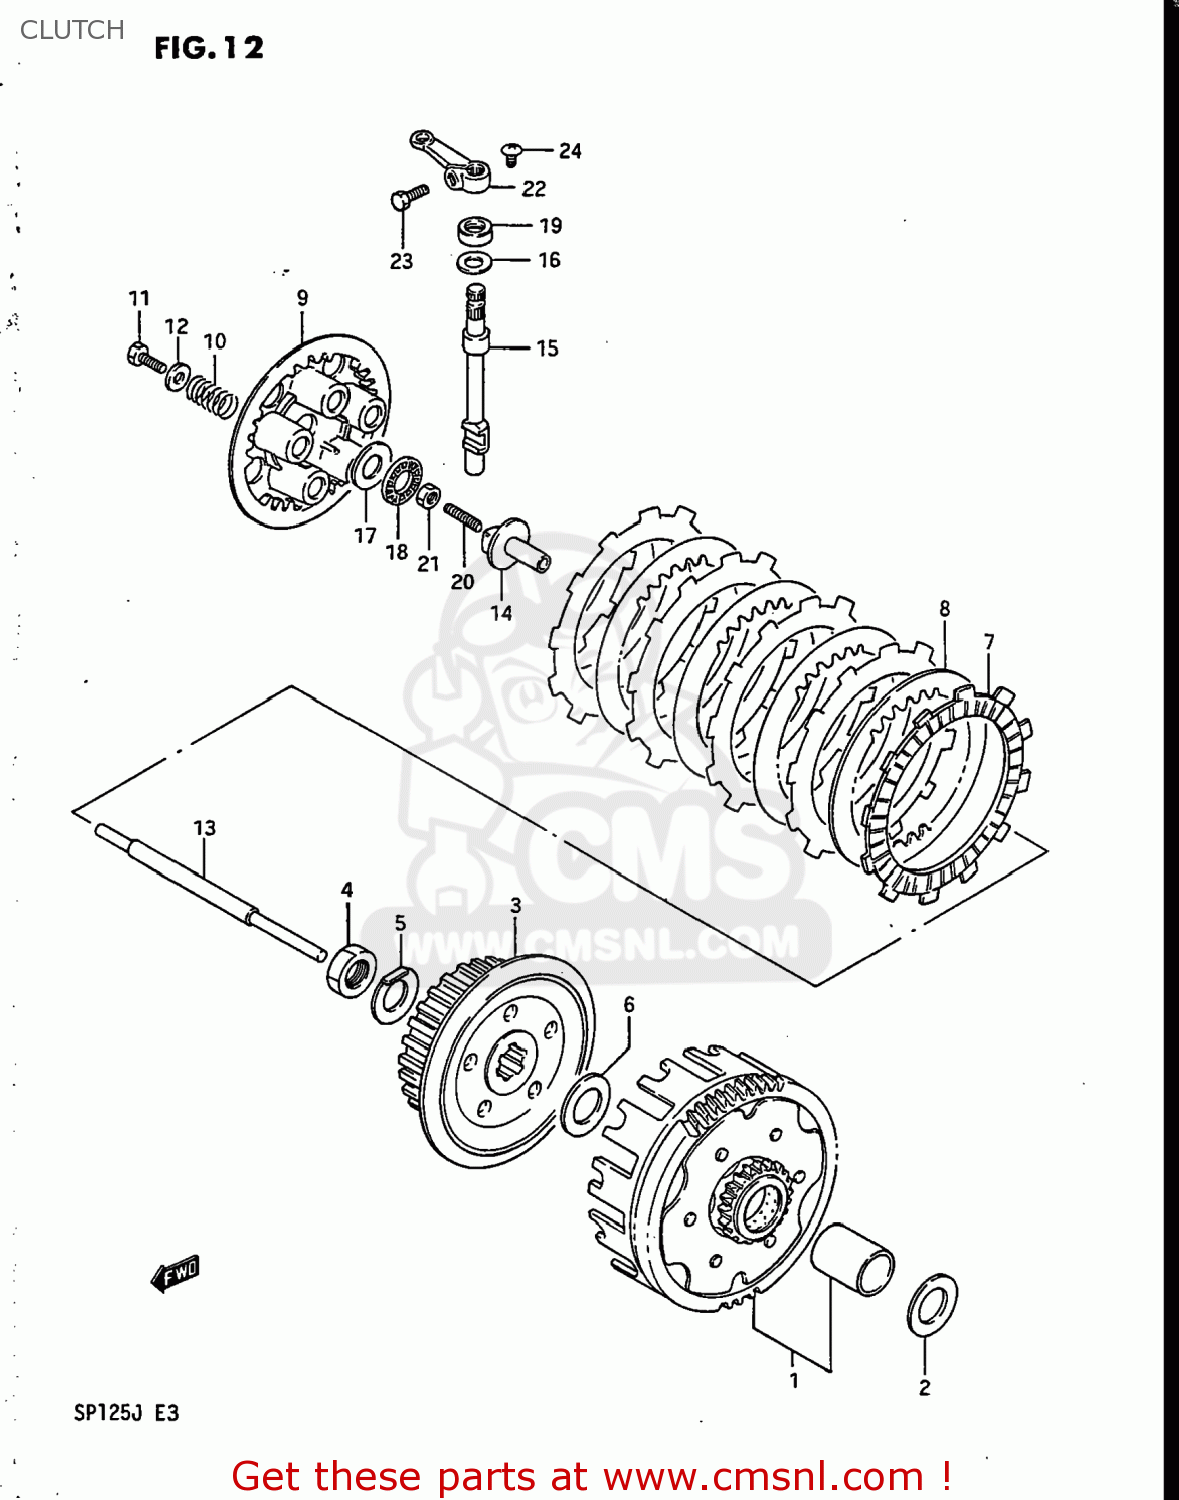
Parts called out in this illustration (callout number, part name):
1	GEAR ASSEMBLY,PRIMARY DRIVE
2	WASHER
3	HUB,CLUTCH SLEEVE
4	NUT
5	WASHER
6	WASHER
7	PLATE,CLUTCH DRIVE (MCA)
8	PLATE,CLUTCH DRIVEN (NAS)
9	PLATE,CLUTCH PRESSURE
10	SPRING
11	BOLT(5X16)
12	WASHER (5.5X16X1.2)
13	ROD,CLUTCH PUSH
14	PIECE,CLUTCH PUSH
15	CAMSHAFT,CLUTCH RELEASE
16	WASHER,THRUST
17	WASHER
18	BEARING(15X28X2)
19	OIL SEAL
20	SCREW(6X25)
21	NUT 6MM
22	ARM,CLUTCH RELEASE
23	BOLT
24	SCREW
